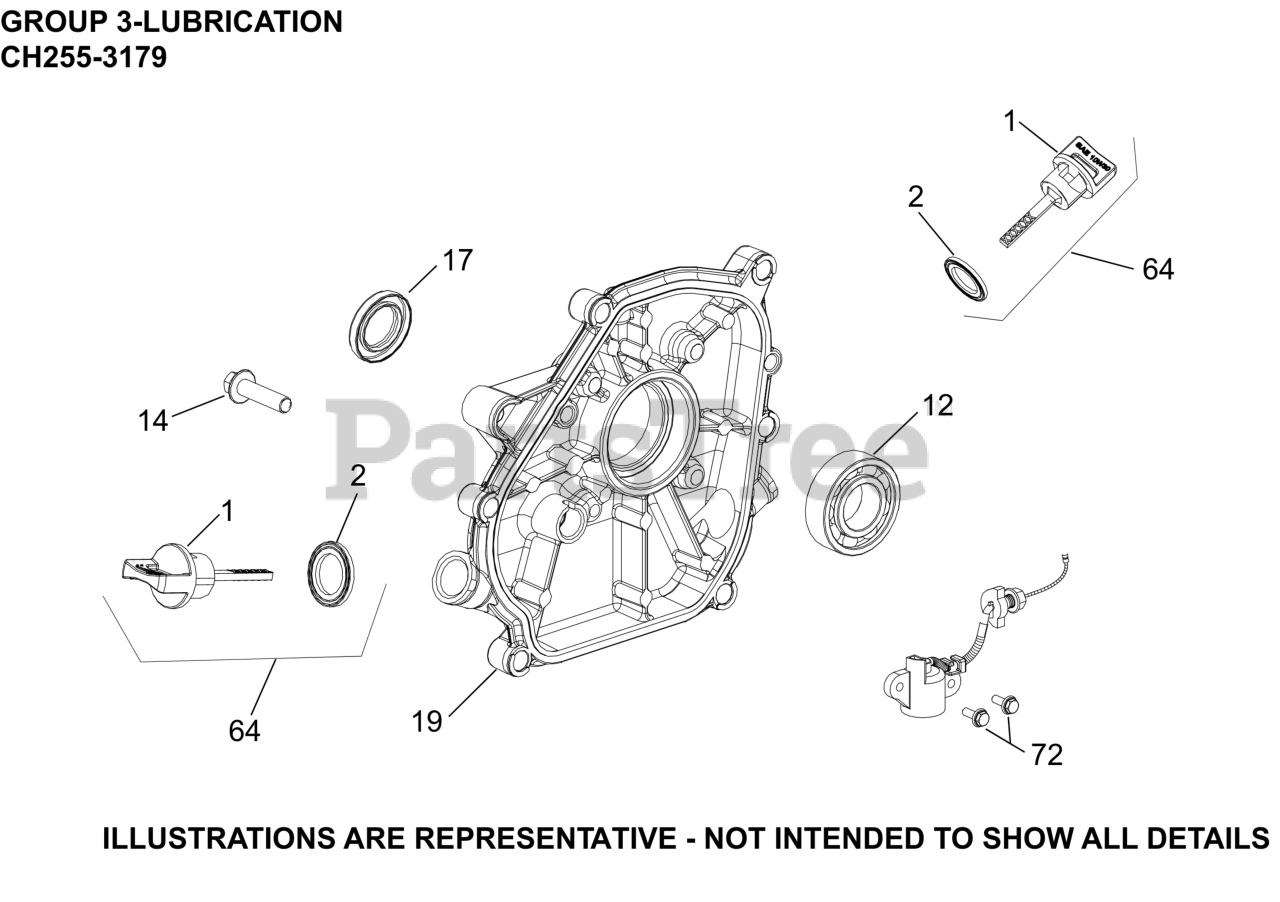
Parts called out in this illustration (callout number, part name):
1	DIPSTICK - USE 17 038 08-S
2	SEAL, DIPSTICK
12	BEARING, BALL
14	SCREW, CLOSURE PLATE
17	SEAL - USE 17 032 29-S
19	PLATE, CLOSURE & BEARING
64	DIPSTICK ASSEMBLY
72	SCREW, M6 X 16
